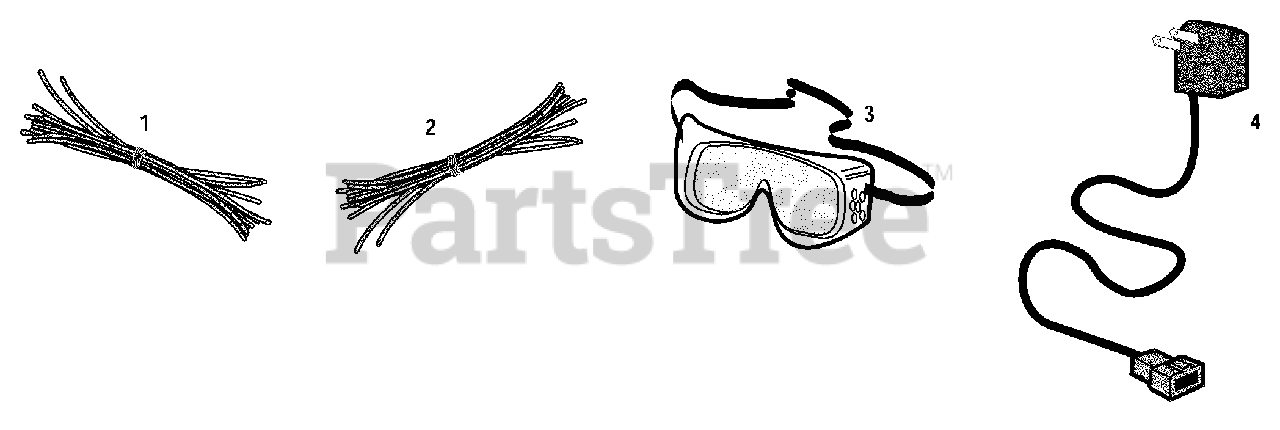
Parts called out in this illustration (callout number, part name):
1	Trimmer String Kit, .155"
2	Trimmer String Kit, .130"
3	Safety Goggles
4	Battery Charger (Electric Start Model)
